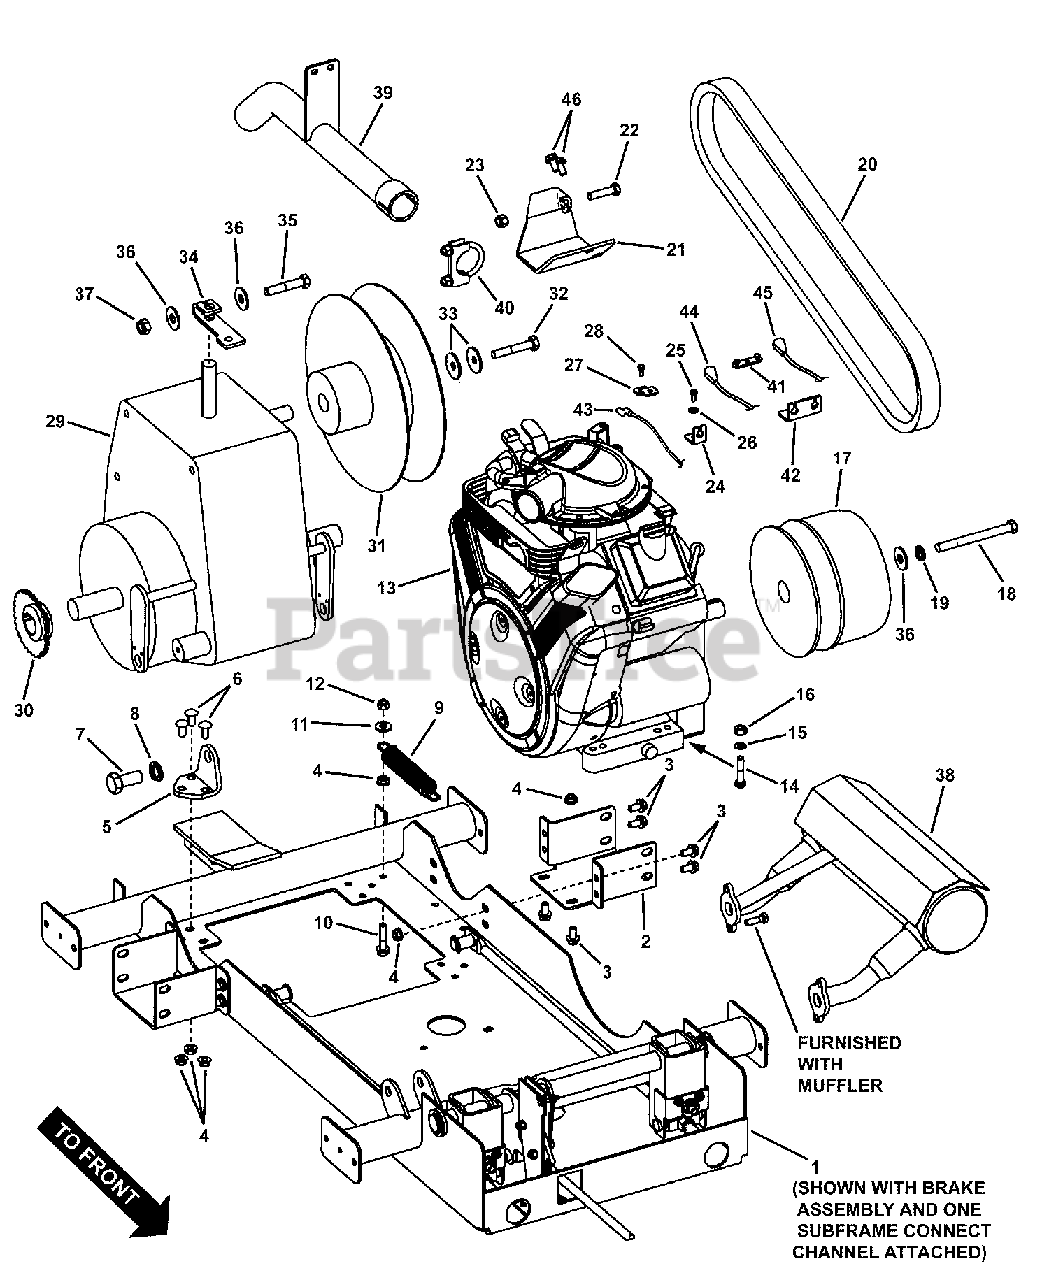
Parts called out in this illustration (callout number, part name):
1	WELDMENT, Drive Base
2	CHANNEL, Subframe Connect
3	BOLT, 5/16-18 x 5/8" Hex Flange Lock, GR 5
4	NUT, 5/16-18 Hex Flange Lock, GR 5
5	BRACKET, Transmission Mount w/Sq. Holes (Black)
6	BOLT, 5/16-18 x 3/4" Short Square Neck Carriage, GR 5
7	SCREW, M16 x 2 x 35MM Hex Head Cap
8	WASHER, 16MM Split Lock
9	SPRING, Brake Return
10	BOLT, 5/16-18 x 1-1/2" Hex Flange Lock, GR 5
11	WASHER, .375 x .875 x .083 Flat
12	NUT, 5/16-18 Hex Nyloc
13	* ENGINE, B&S 16 HP w/Generator Mod. 30544A-0111-E1 (shown)
14	SCREW, 5/16-24 x 1-1/2 Hex Head Cap, GR 5
15	WASHER, 5/16" Split Lock
16	NUT, 5/16-24 Hex, GR 5 or B
17	CLUTCH, CVT Drive
18	SCREW, 7/16-20 x 4-1/2" Hex Head Cap, GR 5
19	WASHER, 7/16" Split Lock
20	BELT, CVT (Cogged; 58.15 effective length)
21	TORQUE BRACKET, Utility Vehicle
22	SCREW, 3/8-16 x 1-1/2" Hex Head Cap, GR 5
23	NUT, 3/8-16 Hex Nyloc
24	ANCHOR, Throttle
25	SCREW, #10-32 x 1/2" Pan Head, Phillips
26	WASHER, #10 External Tooth Lock
27	THROTTLE PLATE, B&S Vanguard
28	SCREW, #10-32 x 1/2" Hex Head Shoulder
29	TRANSAXLE, Tuff Torq KT35C
30	SPROCKET, # 35- 3/8 Pitch
31	PULLEY, CVT Drive
32	SCREW, M10-1.5 x 60 Hex Head Cap (w/nyloc patch)
33	WASHER, Cone
34	SHIFT ARM, CVT
35	SCREW, 7/16-20 x 2-1/4" Hex Head Cap, GR 5
36	WASHER, 7/16" Flat (Type A, Wide)
37	NUT, 7/16-20 Hex Top Lock
38	MUFFLER, 16 HP B&S Vanguard
39	TAILPIPE, UV-2
40	MUFFLER CLAMP, 1-5/8"
41	THROTTLE LINK, B&S Vanguard
42	BRACKET, Throttle Adjustment
43	CABLE, Throttle, 16 HP Vanguard
44	CABLE, Throttle, Pedal, Powerlink
45	THROTTLE, Remote, Powerlink
46	SCREW, M8-1.25 x 16, Hex Head Cap
